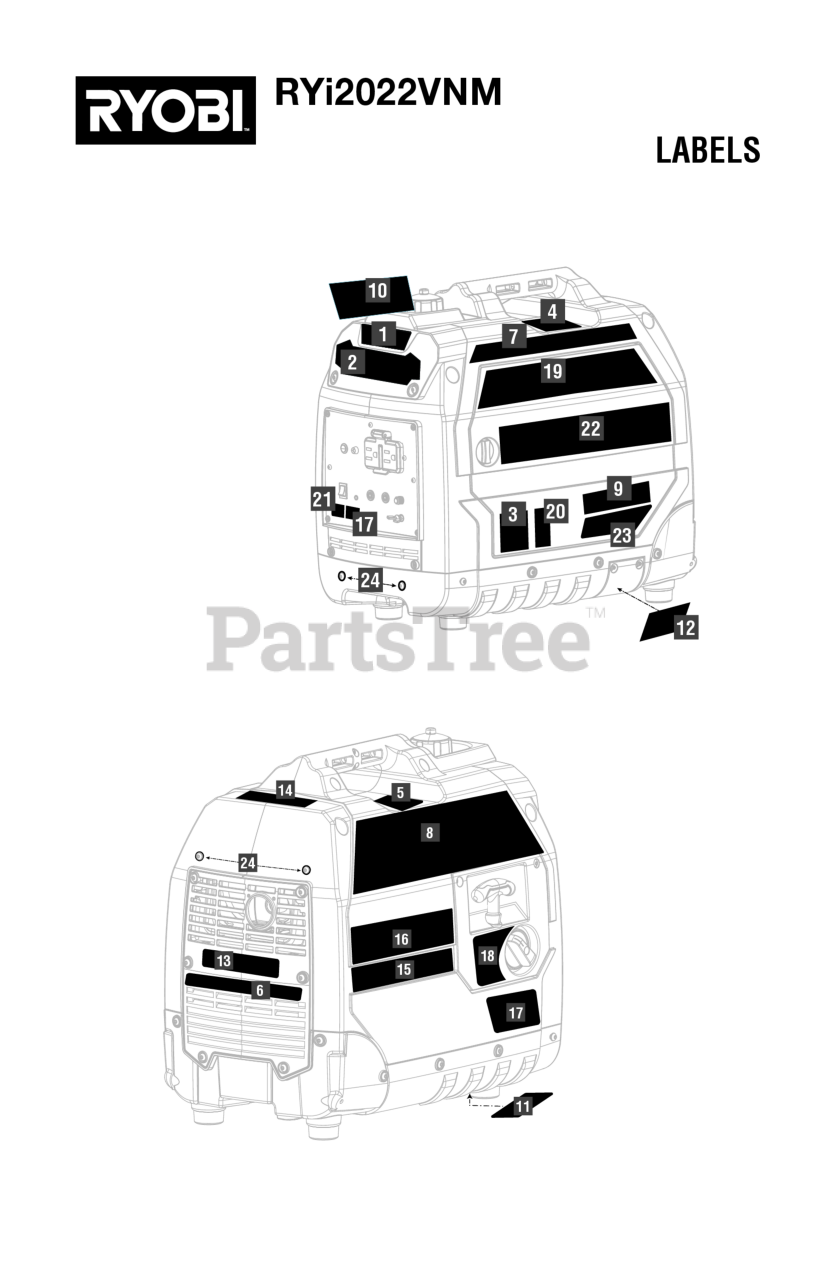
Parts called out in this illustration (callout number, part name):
1	Start Label (Hood)
2	Logo Label
3	Fuel Stabilizer Label
4	CPSC Danger Label
5	Danger Label
6	Ground Warning Label (En/Fr)
7	Fire Distance Label
8	Performance Label (Maintenance Door)
9	Inquires Label (Ryobi)
10	Warning Hangtag
11	Upright Storage Label
12	Internally Placed Maintance Label
13	Combustion Label
14	Exhaust Direction Label
15	Start Label
16	Easy Start Logo Label
17	CO Detect Logo Label
18	Choke Label
19	Performance Label
20	Do Not Tamper Label
21	LED Light Legend Label
22	CO Automatic Shut Down Label
23	Lubricant Label
24	Half Inch Black Round Label
